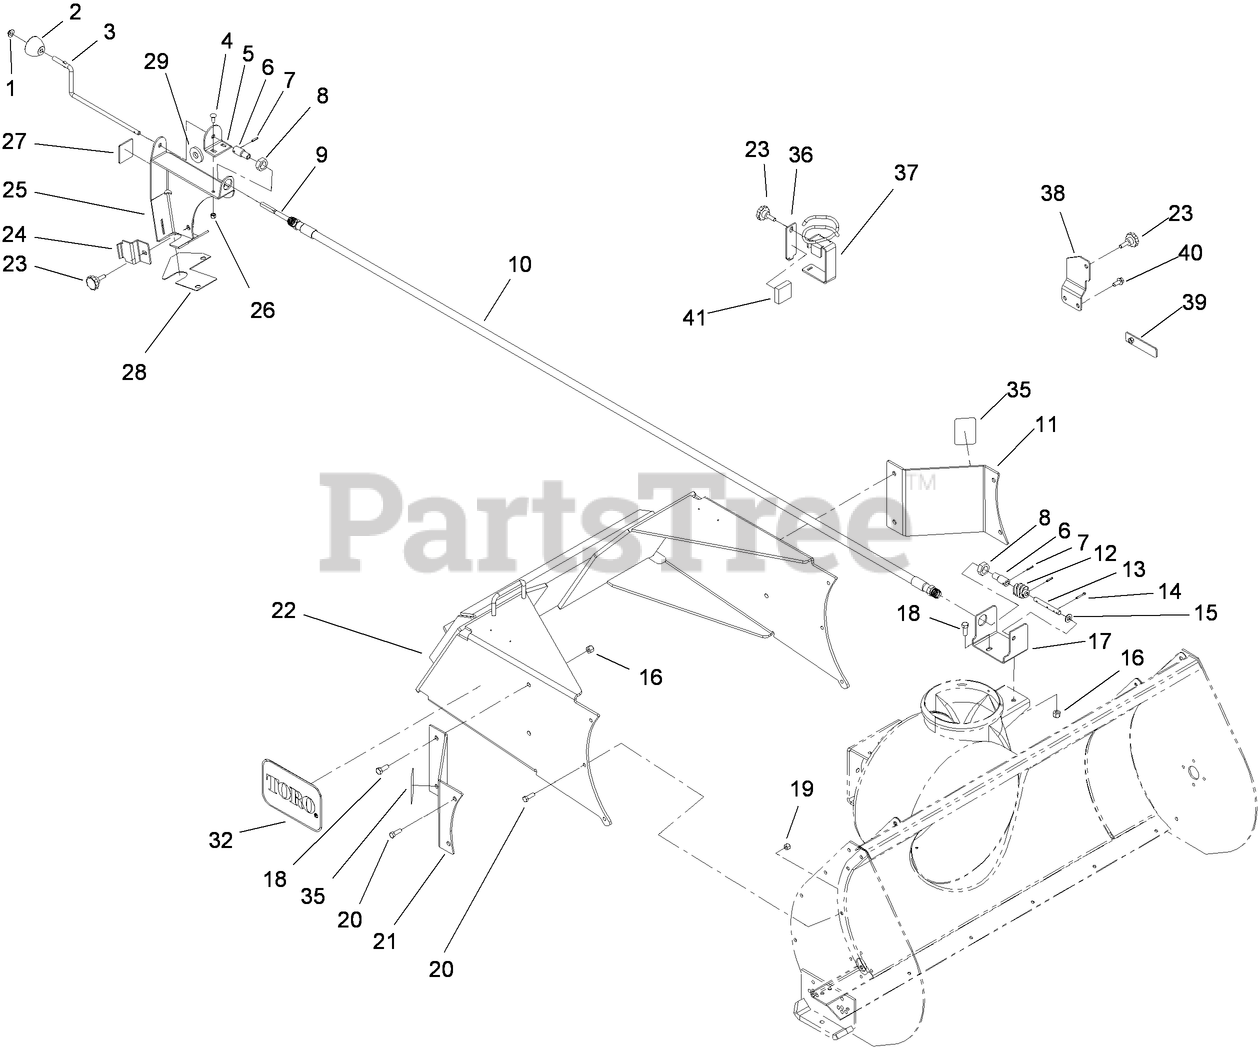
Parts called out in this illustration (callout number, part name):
1	NUT-PUSH
2	KNOB-CHUTE
3	ROD-CONTROL, CHUTE
4	BOLT-CARR
5	BRACKET-ROD, SUPPORT
6	COUPLER
7	PIN-SPRING
8	LOCKNUT
9	SHAFT-FLEXIBLE
10	HOSE ASM
11	PLATE-EXTENSION, LH
12	GEAR-WORM, CHUTE
13	SHAFT-GEAR, WORM
14	PIN-COTTER
15	WASHER-FLAT
16	NUT-LOCK, NI
17	BRACKET-GEAR, WORM
18	SCREW-HH
19	NUT-LOCK, NI
20	SCREW-HH
21	PLATE-EXTENSION, RH
22	SNOWTHROWER MOUNT ASM
23	KNOB-CONTROL, CHUTE
24	BRACKET-CLAMP
25	BRACKET-CONTROL, CHUTE
26	NUT-LOCK, NI
27	DECAL-CHUTE DIRECTION
28	FOAM-CHUTE, CONTROL
29	WASHER-FLAT
32	DECAL
35	REFLECTOR
36	BRACKET-RETAINER
37	RETAINER-HOSE
38	BRACKET,CLAMP
39	PLATE-RETAINER
40	SCREW-HWHTF
41	PAD-RETAINER, BRACKET
